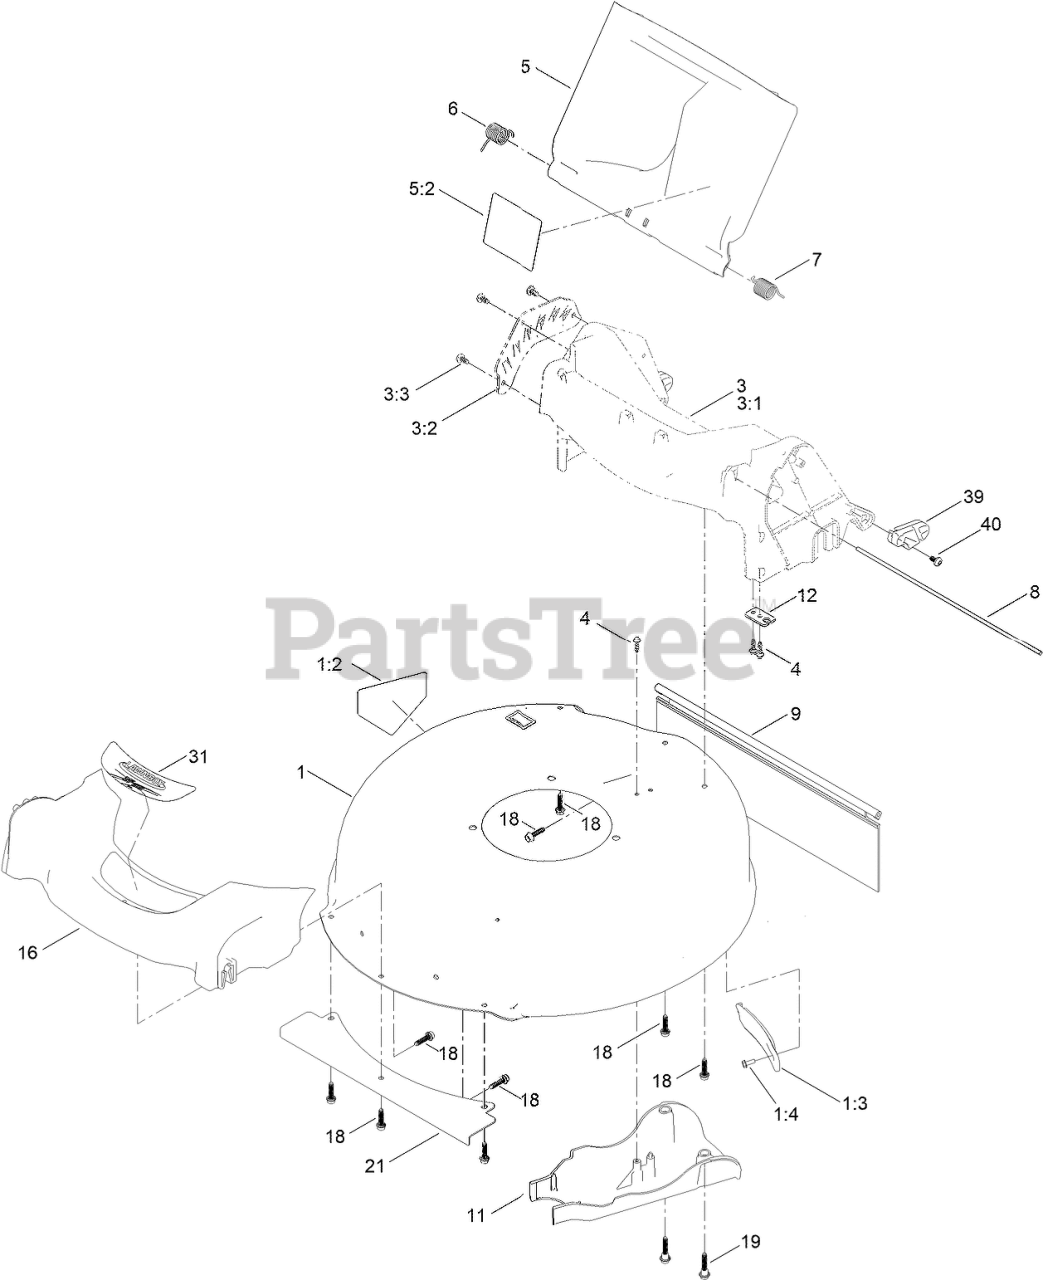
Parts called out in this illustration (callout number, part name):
1	HOUSING ASM
1:2	DECAL-DANGER
1:3	COVER-BELT
1:4	SCREW-TAPTITE
3	CHUTE ASM
3:1	CHUTE-SP/AWD, 21 IN
3:2	PLATE-HOC
3:3	SCREW-PLASTIC,PH
4	SCREW-PLASTIC, HWH
5	REAR DEFLECTOR ASM (60V)
5:2	DECAL-WPM WARNING, 60V
6	SPRING-TORSION
7	SPRING-TORSION
8	ROD-DOOR
9	SHIELD-TRAILING
11	COVER-BELT
12	BRACKET-CABLE
16	BUMPER
18	SCREW-FLANGE, PLASTIC
19	SCREW-SHOULDER, HHF
21	SHIELD-FRONT
31	DECAL-DECK
39	PAD-STOW, SMART
40	SCREW-PLASTIC,PH
